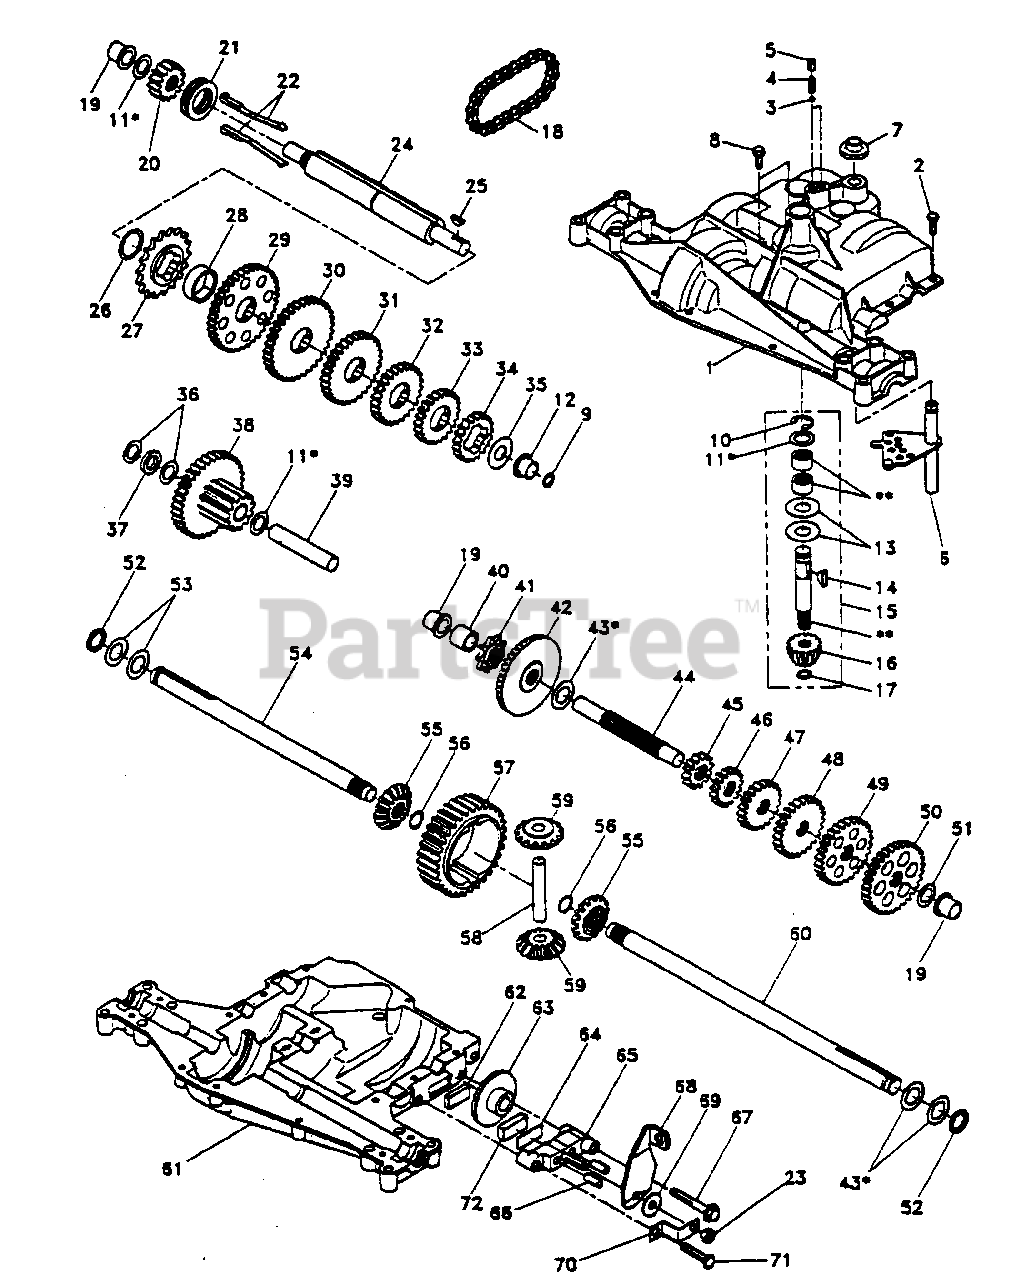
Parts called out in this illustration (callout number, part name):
1	Housing, Upper (AYP part number)
2	Screw, Self-Tapping, Large 1/4-20 x .734 (AYP part number)
3	Ball, Detent (AYP part number)
4	Spring, Detent (AYP part number)
5	Screw, Set (AYP part number)
6	Kit, Shifter Assembly (AYP part number)
7	Boot, Shifter (AYP part number)
8	Screw, Self-Tapping, with Sealer (AYP part number)
9	Square Ring (AYP part number)
10	Ring, Retaining (AYP part number)
11	Assembly, Kit, Shim .625 Shaft (AYP part number)
12	Bearing, Flange (AYP part number)
13	Washer, Plain .632 x 1.38 x .046 (AYP part number)
14	Key, Woodruff, #9 (AYP part number)
15	Assembly, Kit, Input Shaft (AYP part number)
16	Pinion, Bevel, 14 Teeth (AYP part number)
17	Ring, Retaining (AYP part number)
18	Chain, 24 Pitches (AYP part number)
19	Bearing, Flange (AYP part number)
20	Gear, Spur, 14 Teeth (AYP part number)
21	Collar, Clutch (AYP part number)
22	Assembly, Kit, Clutch Keys (AYP part number)
23	Locknut 5/16-24 (AYP part number)
24	Shaft, Intermediate (AYP part number)
25	Key, Woodruff, #61 (AYP part number)
26	Ring, Retaining (AYP part number)
27	Sprocket, 18 Teeth (AYP part number)
28	Spacer (AYP part number)
29	Gear, Spur, 37 Teeth (AYP part number)
30	Gear, Spur, 35 Teeth (AYP part number)
31	Gear, Spur, 30 Teeth (AYP part number)
32	Gear, Spur, 25 Teeth (AYP part number)
33	Gear, Spur, 22 Teeth (AYP part number)
34	Gear, Spur, 19 Teeth (AYP part number)
35	Washer, Plain .640 x 1.37 x .061 (AYP part number)
36	Washer, Plain .632 x 1.00 x .026 (AYP part number)
37	Spacer .630 x 1.00 x .169 (AYP part number)
38	Ass'y, Gear, Combination of 12 & 35 Teeth (AYP part number)
39	Shaft, Idler (AYP part number)
40	Spacer .635 x .875 x .755 (AYP part number)
41	Sprocket, 9 Teeth (AYP part number)
42	Gear, Bevel, 42 Teeth (AYP part number)
43	Assembly, Kit, Shim .750 Shaft (AYP part number)
44	Shaft, Drive (AYP part number)
45	Gear, Spur, 12 Teeth (AYP part number)
46	Gear, Spur, 15 Teeth (AYP part number)
47	Gear, Spur, 20 Teeth (AYP part number)
48	Gear, Spur, 25 Teeth (AYP part number)
49	Gear, Spur, 28 Teeth (AYP part number)
50	Gear, Spur, 31 Teeth (AYP part number)
51	Washer, Plain .632 x 1.00 x .060 (AYP part number)
52	Washer, Neoprene (AYP part number)
53	Washer, Plain .758 x 1.25 x .031 (AYP part number)
54	Axle, L.H. (AYP part number)
55	Gear, Miter, 15 Teeth (AYP part number)
56	Ring, Retaining (AYP part number)
57	Gear, Spur, 32 Teeth (AYP part number)
58	Shaft, Cross (AYP part number)
59	Gear, Miter, 15 Teeth (AYP part number)
60	Axle, R.H. (AYP part number)
61	Housing, Lower (AYP part number)
62	Puck, Friction (AYP part number)
63	Disc, Brake (AYP part number)
64	Spacer (AYP part number)
65	Jaw, Brake (AYP part number)
66	Pin, Dowel (AYP part number)
67	Screw, Self-Tapping, Large 5/16-18 x 2.25 (AYP part number)
68	Lever, Actuating (AYP part number)
69	Washer, Plain .321 x 1.00 x .055 (AYP part number)
70	Bracket, Anti-Rotation (AYP part number)
71	Screw, Self-Tapping, Large 5/16-18 x 1.44 (AYP part number)
72	Puck, Friction (AYP part number)
73	Grease (AYP part number)
